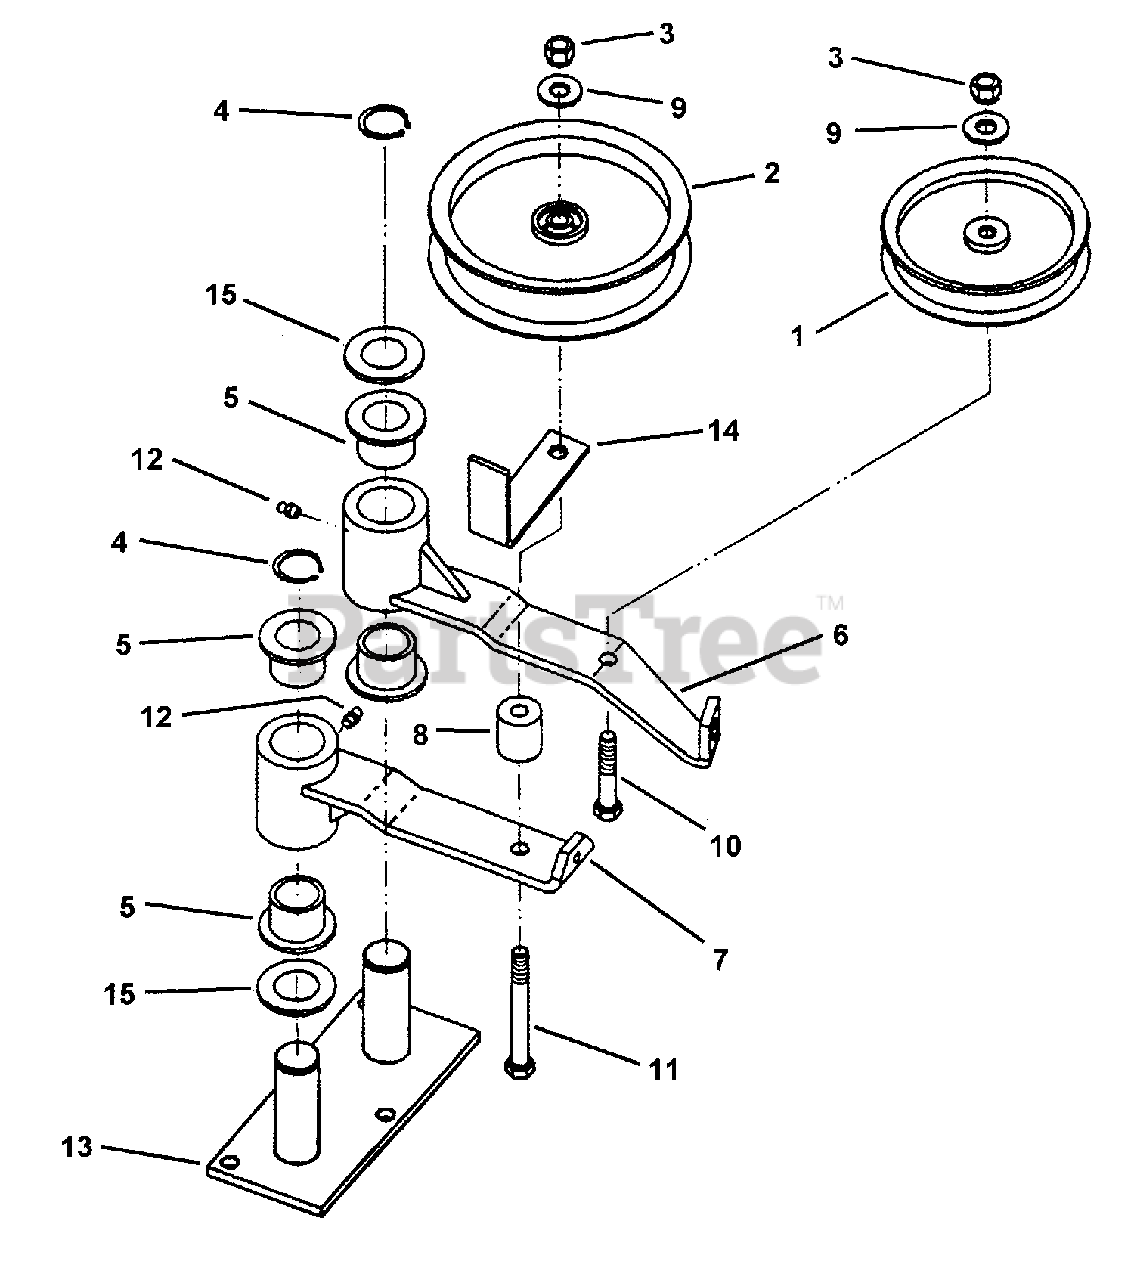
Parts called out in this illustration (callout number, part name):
1	PULLEY, Idler
2	PULLEY, Flat Idler, 5" O.D.
3	NUT, 3/8-16 HEX NYLON LOCK
4	RING, 1" External Retaining
5	BUSHING
6	WELDMENT, Idler Arm, Secondary
7	WELDMENT, Idler Arm, Primary
8	SPACER, Idler Pulley
9	WASHER, 3/8" Flat
10	BOLT, 3/8-16 X 2, GD5, CZ
11	BOLT, 3/8-16 x 3-1/4" Hex Head Cap, GR 5
12	LUBE FITTING, 1/4-28 Straight
13	WELDMENT, Idler Pivot
14	RETAINER, Belt - Idler
15	BUSHING, 1" I.D. Machine
